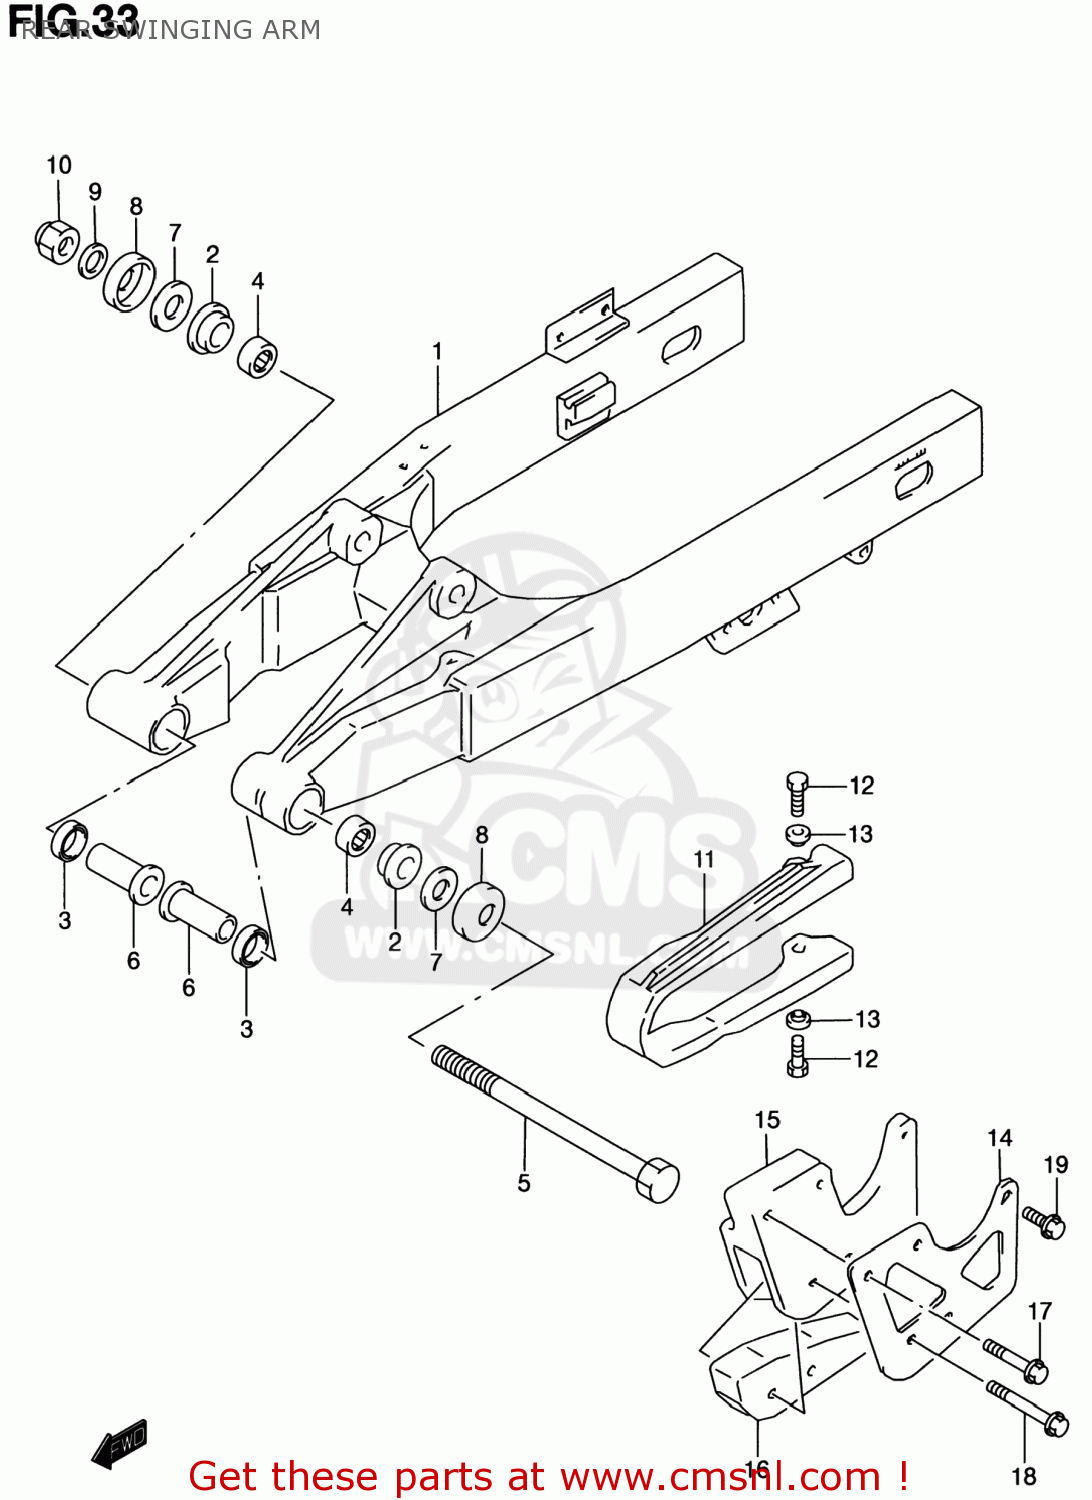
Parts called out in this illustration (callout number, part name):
1	SWINGINGARM ASSY,RR
2	BUSHING,SWGARM PIVOT
3	SEAL,OIL(17X24X3)
4	BEARING(17X24X30)
5	SHAFT,RR SWINGINGARM PIVOT
6	SPACER,RR SWGARM PIVOT
7	WASHER
8	COVER,SWGARM PIVOT
9	WASHER
10	NUT 12MM
11	BUFFER,CHAIN TOUCH DEFENSE
12	BOLT
13	WASHER
14	PLATE,GUIDE CHAIN OUTER
15	GUIDE,CHAIN
16	DEFENSE,CHAIN GUIDE
17	BOLT,G/S SWITC
18	BOLT
19	BOLT
